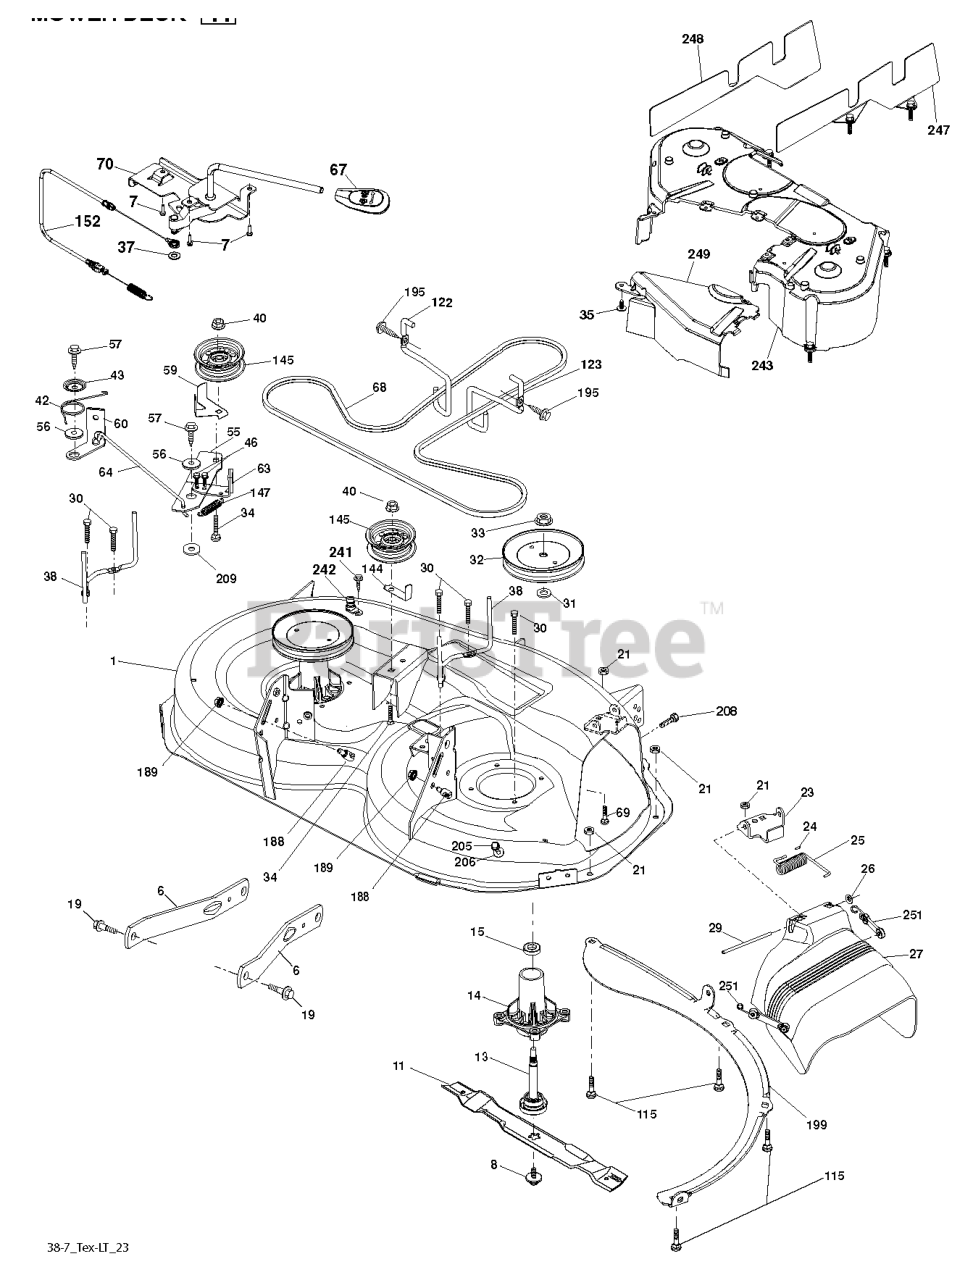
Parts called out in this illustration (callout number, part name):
6	ARM.SUSPENSION.MOWER.R
7	SCREW.#10 X 0.750.BOS
8	BOLT.WASHER.ASM.7/16-2
11	BLADE 38" PREMIUM
13	SHAFT.ASM.MDRL.N/GREASE.38
14	RP.HOUSING.MANDREL.4PT.
19	BOLT.SHOULDER
21	LOCKNUT
23	BRKT.DEFLECTOR.38"2005+
24	CAP-SLEEVE LT
25	SPRING.TORSION.DEFLECT
26	NUT PUSH M
27	SHIELD ASM.DFLCTR MWR.38-7"BLK
29	ROD.HINGE
30	SCREW, WASHER HEAD
31	WASHER.SPACER.MANDREL
32	PULLEY.MANDREL.5.0.PD.38"
33	NUT.FLANGE.LOCK.TOP
34	BOLT.3/8-16X1.50
35	FASTENER.XMAS.TREE
37	WASHER
38	KEEPER BELT LH MANDREL
40	NUT LOCK FLG 3/8-16 UNC
42	SPRING.TORSION.BRAKE
43	SRPING.TORSION.RETAINE
46	SCREW.1/4-20X5/8
56	SPACER.RETAINER
57	SCREW 3/8-16X1
59	GUARD, BELT
60	ARM BRAKE MOWER RH 38"
63	RP ARM.BRAKE.MOWER.38"LH.TEX
64	LINK BRAKE
67	HANDLE.CLUTCH.CABLE.LT
69	BOLT
70	CLUTCH.ASM.MANUAL.LT.PRED
115	BOLT.CARR.5/16-18X5/8.SHORT
122	KEEPER BELT ENGINE LH
123	KEEPER BELT RH
144	KEEPER BELT
145	PULLEY.IDLER.48"PRIMARY
147	SPRING RETURN
152	CABLE.CLUTCH.MANUAL.
188	STUD.FASTNER.W/ANTI-ROTATE
189	NUT LOCK HEX FLANGE 5/16-18
195	SCREW, 3/8-16X3/4
199	BAFFLE.VORTEX.FRONT.38"
205	SCREW
208	SCREW 3/8-16X1/2
209	WASHER 12/32X2X10GA
241	SCREW.TT.#10-32X.5.3/8.FLANGE
242	PORT.WASHOUT
247	SHIELD RIGHT
248	SHIELD LEFT
249	COVER CABLE CLUTCH
251	ELASTIC STRAP KIT
